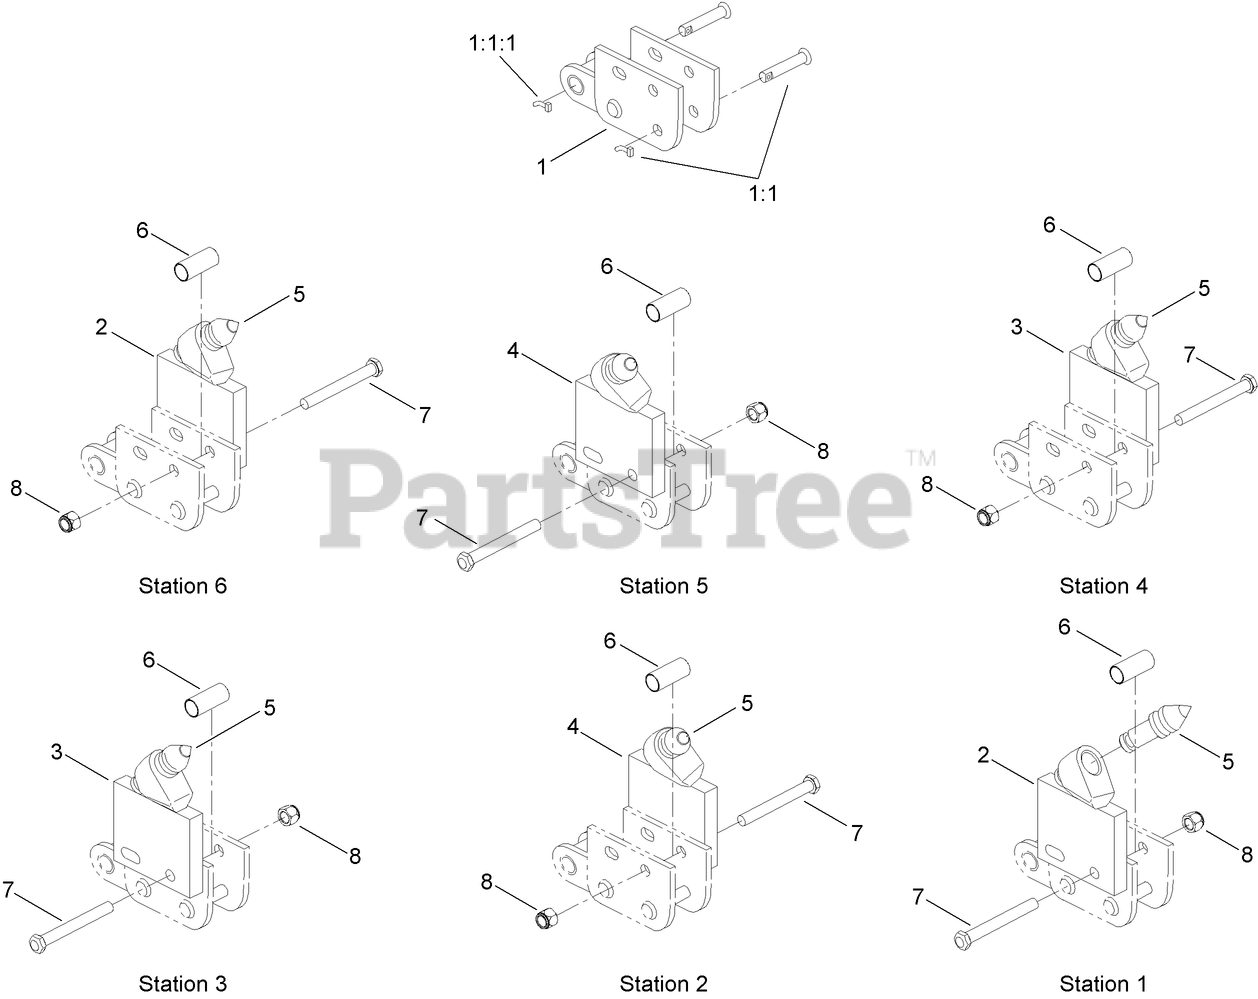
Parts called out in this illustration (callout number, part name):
1	CHAIN REPAIR LINK ASM
1:1	NOTCHED PIN AND KEEPER ASM
1:1:1	PIN-KEEPER
2	HOLDER-BIT, LH
3	HOLDER-BIT, STRAIGHT
4	HOLDER-BIT, RH
5	BIT AND CLIP, CARBIDE
6	SPACER-TUBE, OUTSIDE MOUNT
7	BOLT-HH
8	NUT-LOCK
